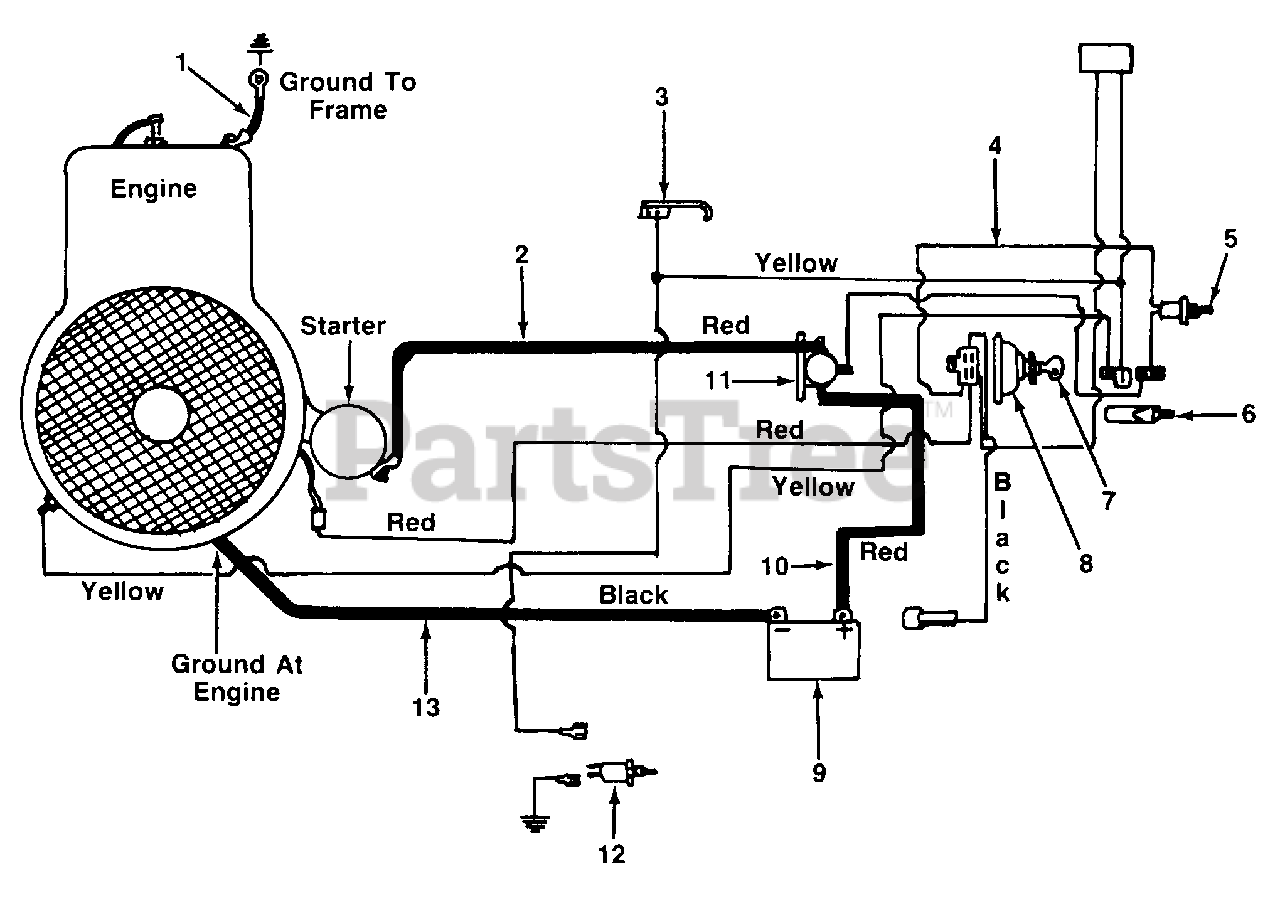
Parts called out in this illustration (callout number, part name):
3	SPRING-SWITCH
4	WIRE HARNESS
5	SWITCH
6	SWITCH-SAFETY
7	KEY-IGN (SET OF TWO)
8	SWITCH-IGNITION
9	BATTERY
11	SOLENOID
12	SWITCH-SAFETY
